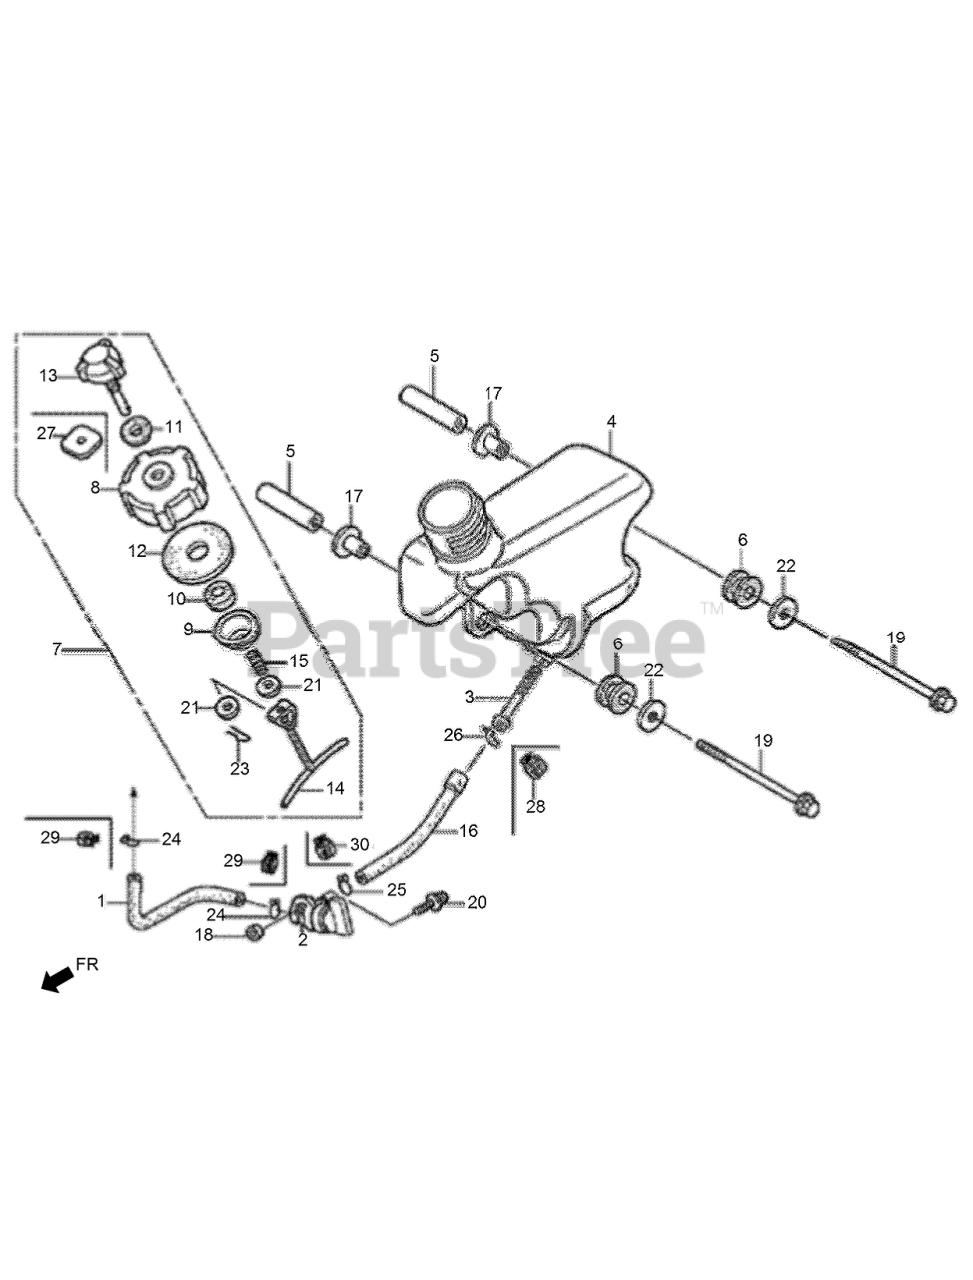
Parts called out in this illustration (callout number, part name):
1	TUBE B-FUEL (from S/N 1005402)
1	TUBE B-FUEL (to S/N 1005401)
2	COCK ASM-FUEL
3	STRAINER-FUEL
4	TANK-FUEL (to S/N 1003833)
4	TANK-FUEL (from S/N 1003834)
5	COLLAR-TANK SETTING
6	RUBBER A-TANK MOUNTING
7	CAP ASM-FUEL TANK (to S/N 1002356)
7	CAP ASM-FUEL TANK (from S/N 1002357 to 1003184)
7	CAP ASM-FUEL TANK (from S/N 1003185)
8	BODY-FUEL CAP (to S/N 1003184)
8	BODY-FUEL CAP (from S/N 1003185)
9	INNER-FUEL CAP
10	SPONGE-FUEL CAP BREATHER
11	PACKING-VALVE (to S/N 1002356)
12	PACKING-FUEL CAP
13	BREATHER VALVE ASM (to S/N 1002356)
13	BREATHER VALVE ASM (from S/N 1002357)
14	LINK-FUEL CAP
15	SPRING-FUEL CAP
16	TUBE-FUEL (from S/N 1005402)
16	TUBE-FUEL TANK (to S/N 1005401)
17	COLLAR-CANISTER MOUNTING
18	COLLAR-FR WINKER
19	BOLT-FLANGE-6X65
20	SCREW-WASHER-5X10
21	WASHER-PLAIN-4MM
22	WASHER-PLAIN-6MM
23	PIN-LOCK-4MM
24	CLIP-TUBE (to S/N 1005401)
25	CLIP-TUBE (to S/N 1005401)
26	CLIP-TUBE (to S/N 1005401)
27	TUBE-FUEL (from S/N 1002357)
28	CLAMP-TUBE (from S/N 1005402)
29	CLAMP-TUBE (from S/N 1005402)
30	CLAMP-TUBE (from S/N 1005402)
